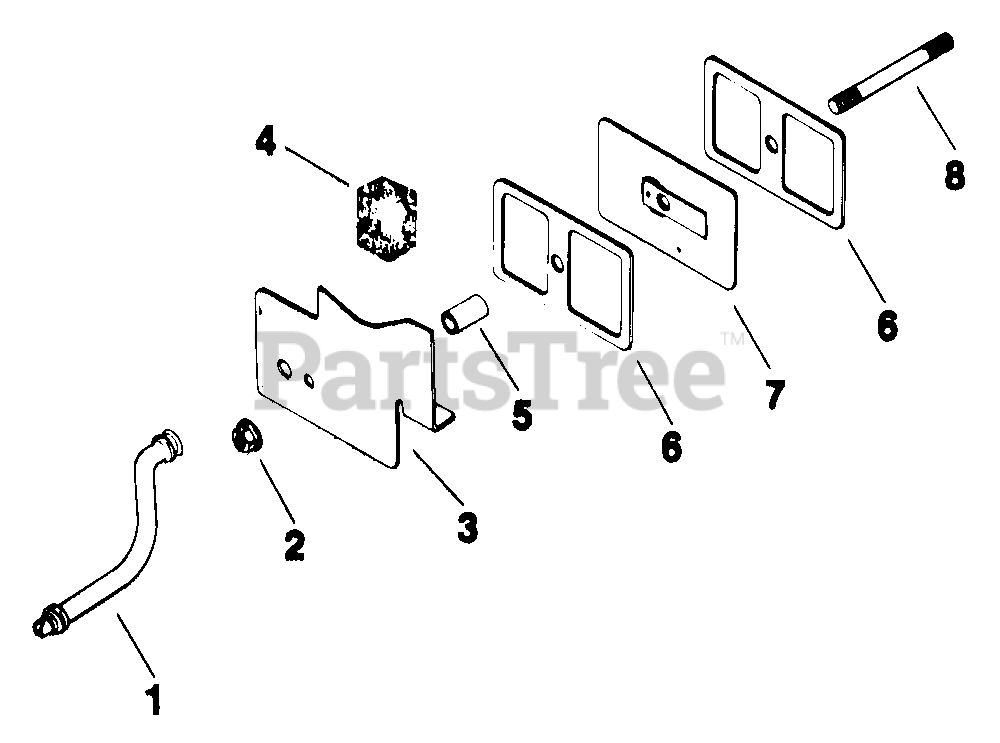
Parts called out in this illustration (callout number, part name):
1	HOSE
1	HOSE, BREATHER
2	PALNUT, 1/4-20
3	VALVE COVER ASSEMBLY
4	FILTER, BREATHER
5	SEAL, BREATHER
7	BREATHER - DISCONTINUED
8	STUD,1/4-20x3-9/16"
